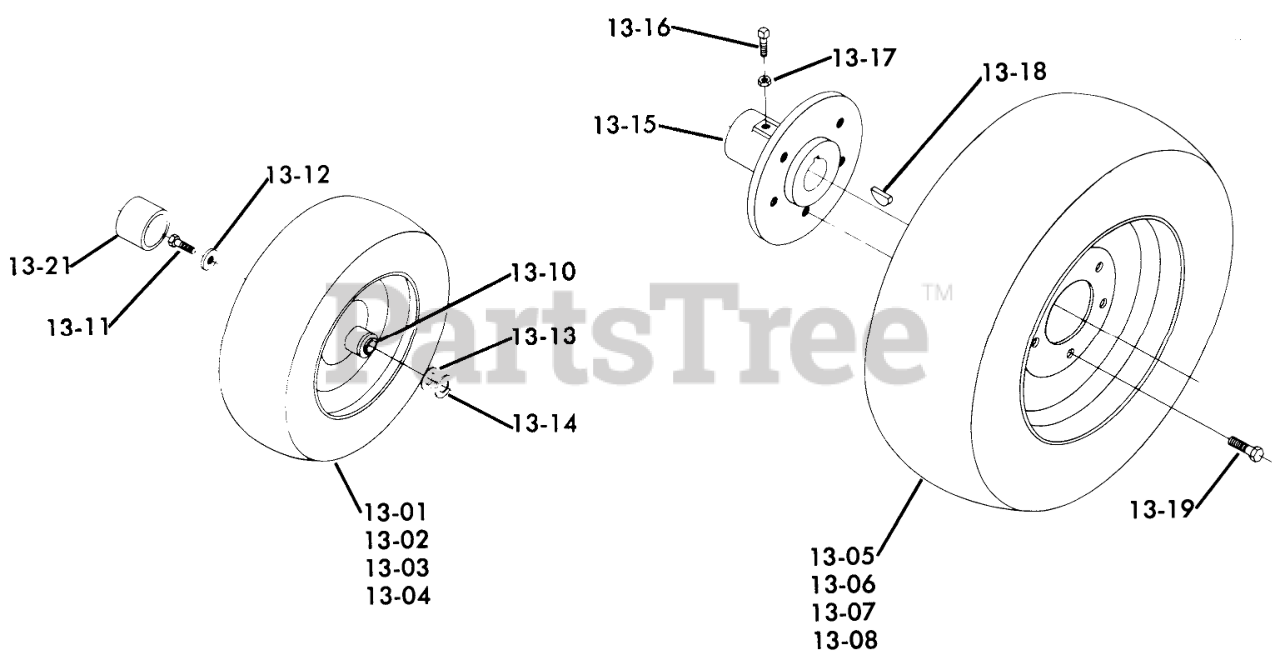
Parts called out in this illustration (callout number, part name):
13-01	ASSY-WHEEL & TIRE
13-02	WHEEL ASSY
13-03	TIRE TURF SAVER 16X6.50-8
13-04	Tube
13-05	Wheel and Tire
13-05	Wheel & Tire Assembly
13-06	Wheel
13-07	Tire
13-07	Tire-Cleat, Rear
13-08	TUBE-INNER
13-09	VALVE
13-10	Bearing
13-11	Bolt
13-12	WASHER
13-13	WASHER
13-14	WASHER-SHIM
13-15	Hub Rear
13-16	Screw-Set
13-17	Nut
13-18	KEY-WOODRUFF
13-19	Lug Nut
13-21	HUB CAP
